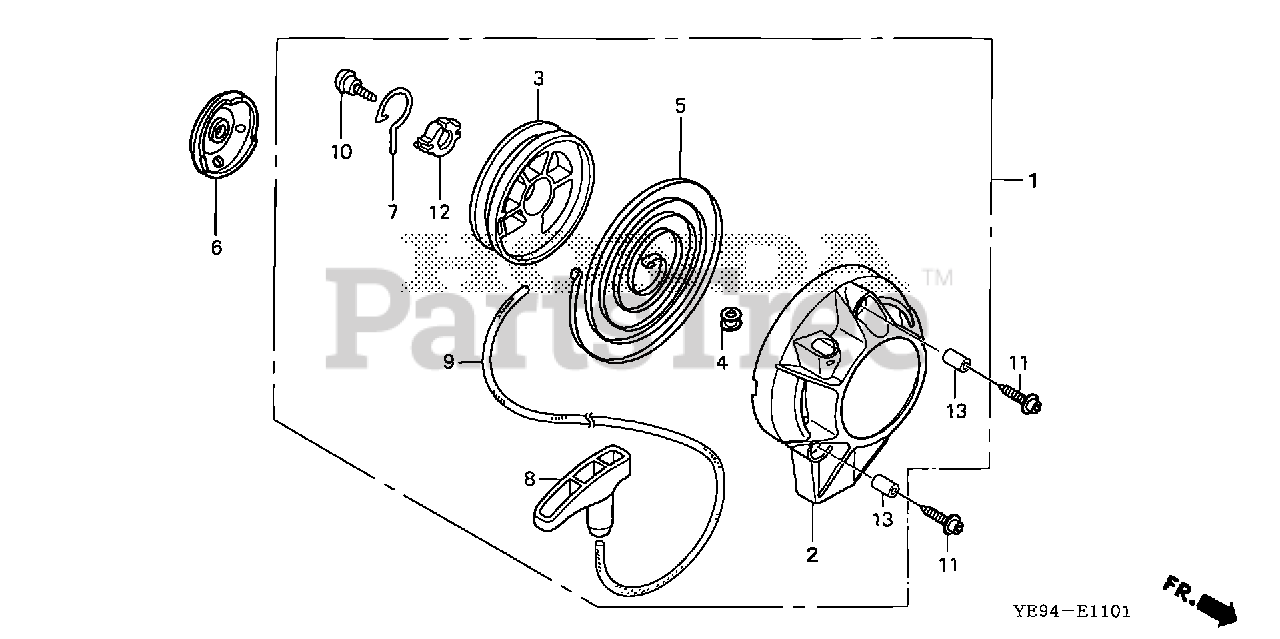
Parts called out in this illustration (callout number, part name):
1	STARTER ASSY., RECOIL (FOR U.S.A.)
2	CASE, RECOIL STARTER
3	REEL, RECOIL STARTER
4	GUIDE, ROPE
5	SPRING, RECOIL STARTER
6	PULLEY, RECOIL STARTER
8	KNOB, RECOIL STARTER
9	ROPE, RECOIL STARTER
10	SCREW, SETTING
11	BOLT, SOCKET (5X16)
13	COLLAR A, HEAD COVER
